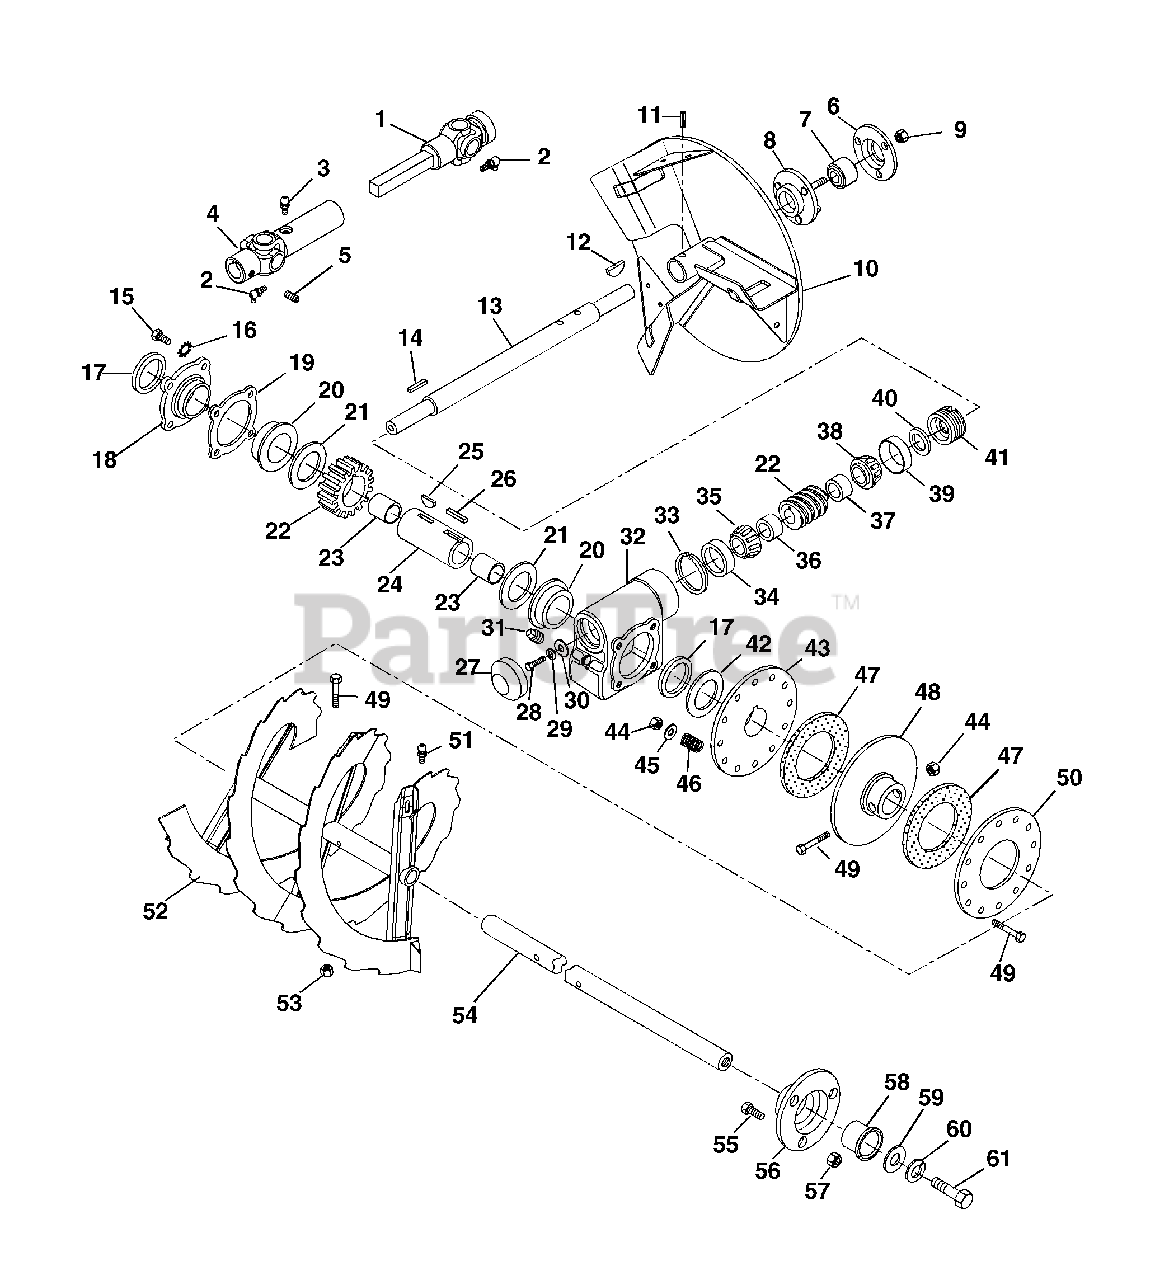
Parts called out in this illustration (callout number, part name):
1	Shaft-Prop, Square Bar
2	Fitting-Lube 90°.
3	Fitting-Lube .25-28 x .46
4	U-Joint-Female
5	Screw-Set .38-16 x .38 Socket Head Cup Point
6	Bearing Flange
7	Bearing-Ball 1.0 x 2.0 x .56
8	Bearing Flange
9	Nut-Locking-Center .25-20
10	Fan, 16"
11	Pin-Roll .313 x 1.75
12	Key-Woodruff .1875" x .875"
13	Worm Shaft
14	Key-Square .188 x 1.0 x .188
15	Bolt-Hex .25-20 x .875
16	Washer-Lock External .250 ID
17	Seal 1.625 x 2.125 x .250
18	Gearcase Cover
19	Gasket
20	Bushing-Flange 1.625 x 1.87 x 1.68 x 2.25
21	Washer-Flat-Steel 1.625 x 2.5 x .012
22	Worm & Gear Service Assembly
23	Bushing-Sleeve 1.125 x 1.250 x 1.000
24	Gear Case Shaft
25	Key-Feather .25 x .875 x .25
26	Key-Square .25 x .625 x .375
27	Dust Cap
28	Bolt-Hex .31-18 x .75 Grade 5
29	Washer-Lock .31 x .078
30	Washer-Flat-Steel .344 x .688 x .065
31	Pipe Plug
32	Gearcase
33	Ring-Retaining-Internal 1.78 x .062
34	Bearing-Cup 1.78 x .475
35	Bearing-Cone .750 x .61
36	Bearing Spacer 1.12 x 1.52 x .5
37	Bearing Spacer
38	Bearing-Cone 1.0 x .58
39	Bearing-Cup 1.980 x .420
40	Seal 1.125 x 1.375 x .125
41	Adjustment Plug
42	Washer-Flat-Steel .344 x .688 x .065
43	Driver
44	Nut-Locking-Top .312-18
45	Washer-Flat-Steel .323 x .625 x .065
46	Spring-Compression .156 x .665 x .75
47	Friction Disc
48	Driven Plate
49	Bolt-Hex .31-18 x 2.00 Grade 5
50	Pressure Plate
51	Fitting-Lube .25-.28 x .256
52	Auger-Right 40"(005)
52	Rake-Right 48"(006)
52	Auger-Left 40"(005)
52	Rake-Left 48"(006)
53	Nut-Locking-Center .31-18
54	Shaft, 40" 1.12 Dia. (005)
54	Shaft, 48"(006)
55	Bolt-Serrated Neck Slotted .25-20 x .50
56	Support-Bearing
57	Nut-Locking-Flange .250-20
58	Bushing-Flange 1.000 x 1.12 x .62 x 1.50
59	Washer-Flat-Steel .511 x 1.441 x .125
60	Washer-Lock .500 x .151
61	Bolt-Hex .50-13 x 1 Grade 5
